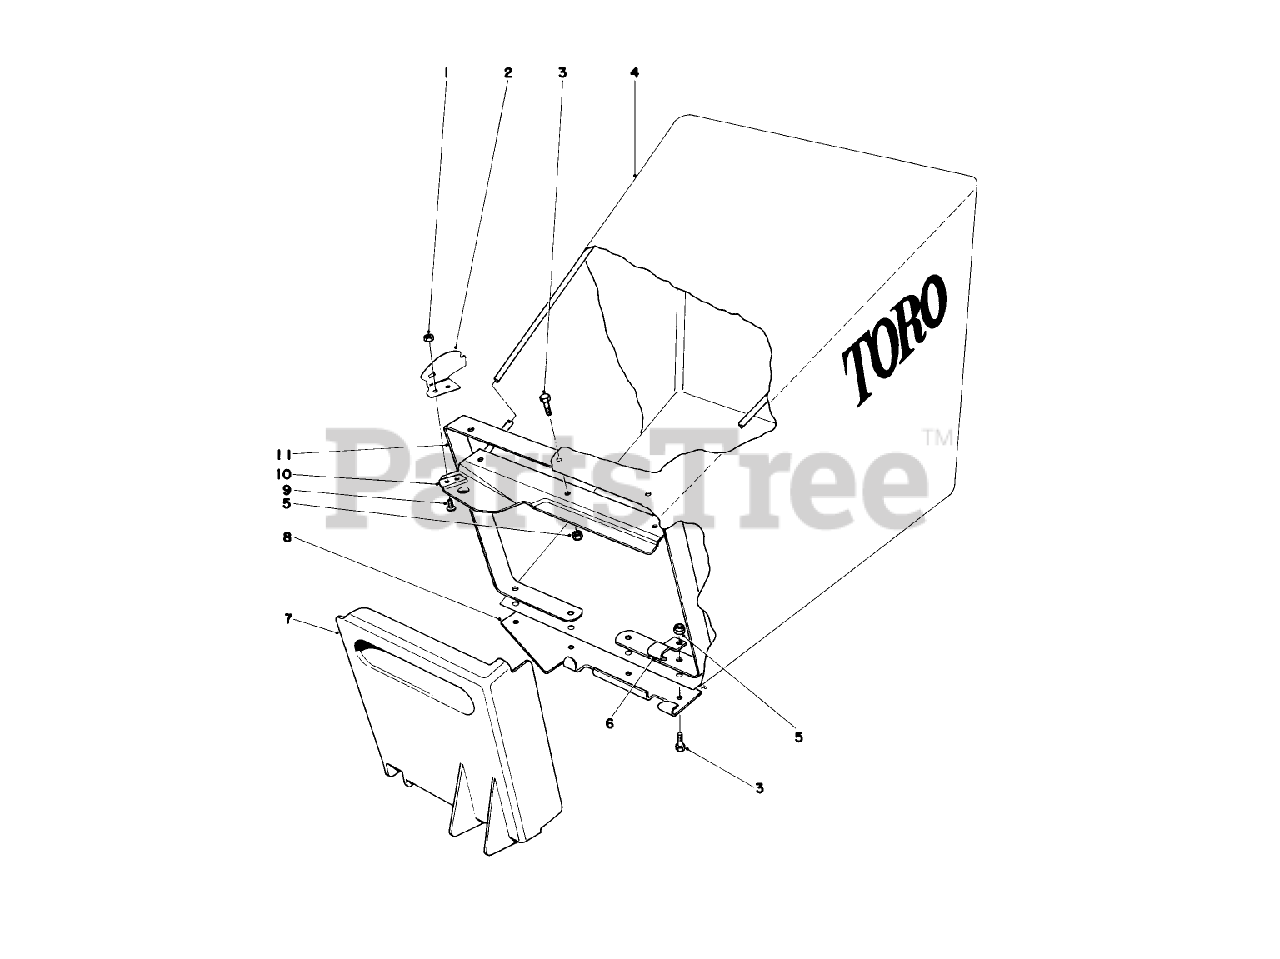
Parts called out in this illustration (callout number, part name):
3	SCREW-HWH
5	NUT-LOCK, SIDE
7	BAG DOOR
11	LOWER BAG FRAME
